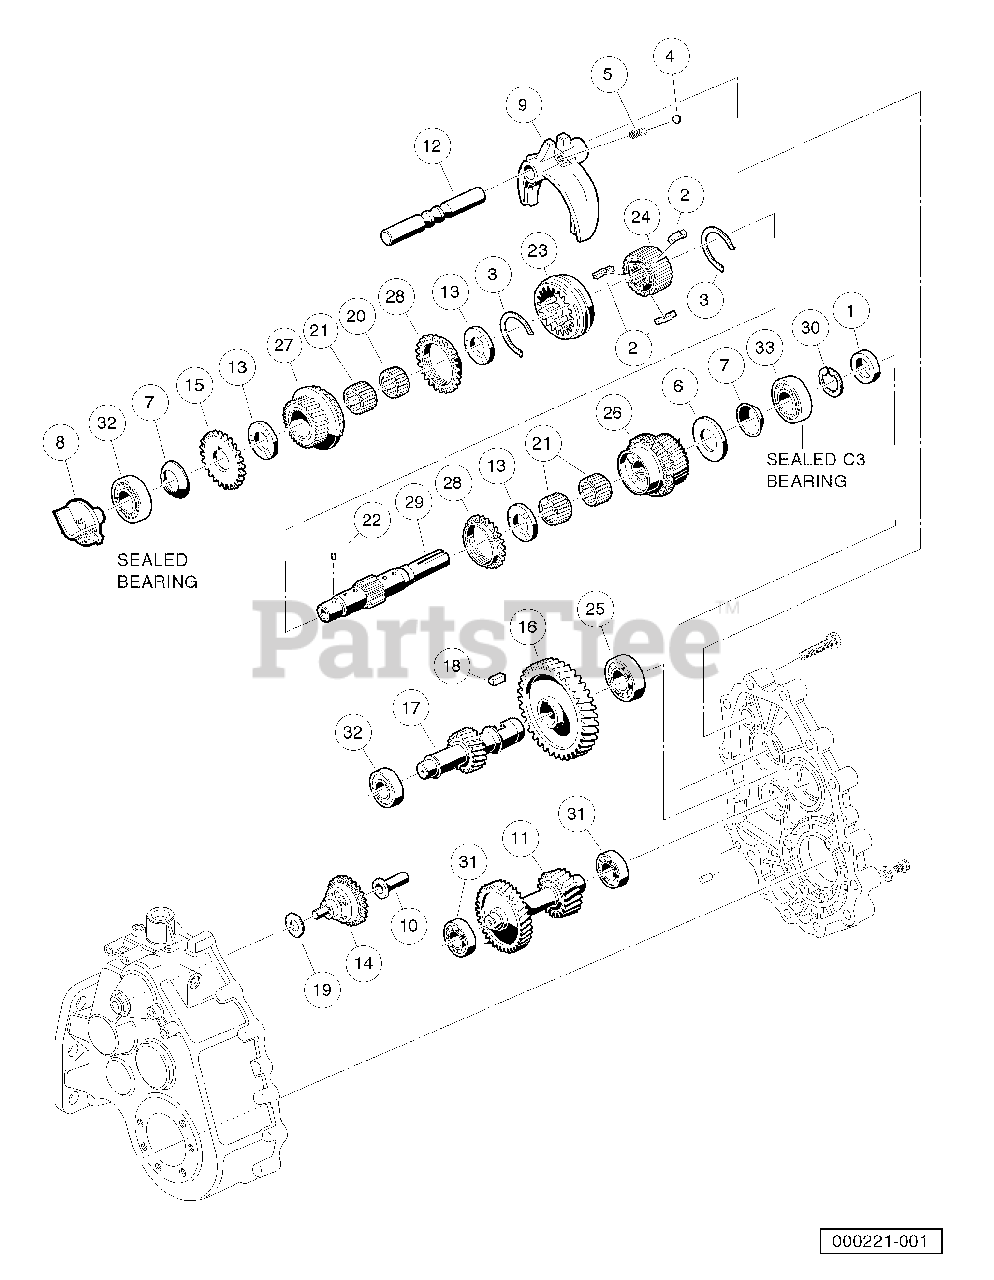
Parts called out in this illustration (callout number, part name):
2	Synchro Insert
3	Synchro Spring
4	Shifter Ball
5	Shifter Spring
6	Washer, Thrust
7	Washer, Spring
9	Fork - Shift
10	Sleeve, Governor
11	Gear, Cluster
12	Rod, Shift
13	Plate, Thrust
14	Governor Assembly
15	Gear, Spur
16	Gear, Helical
17	Gear, Helical
20	Needle Bearing
21	Needle Bearing
22	Pin, .116" Dia X 0.264 Dowel
23	Sleeve, Synchro
24	Hub, Synchro Clutch
25	Bearing, Ball
26	Gear Assembly, 16-Degree Synchro
27	Gear Assembly, 16-Degree Rear Synchro
28	Ring, 16-Degree Synchronizer
29	Shaft, Trans, with Circlip
32	Bearing, Ball, Sealed
33	Bearing, Ball, Sealed
